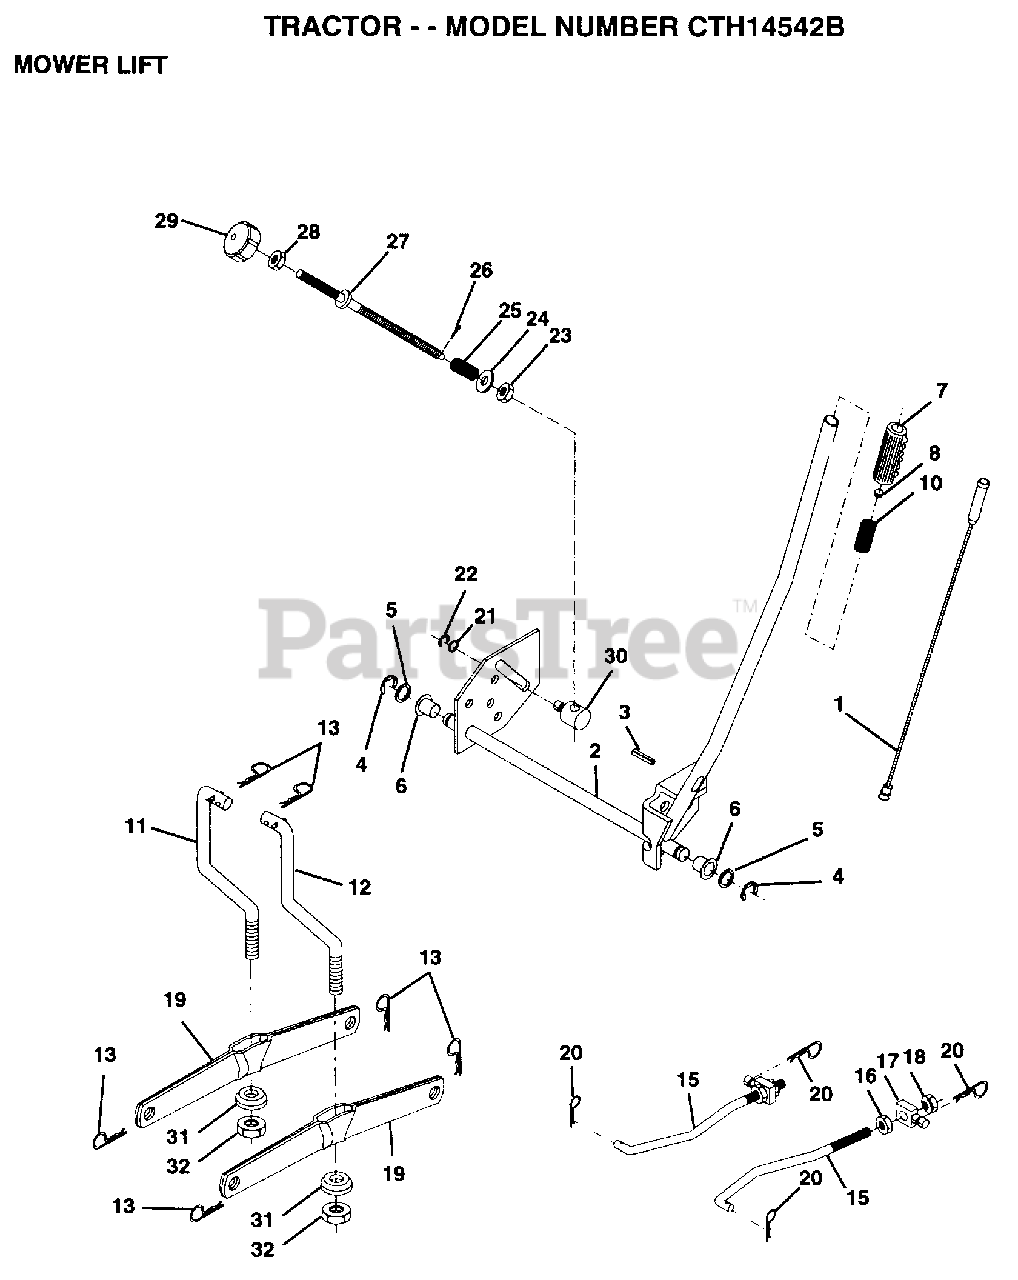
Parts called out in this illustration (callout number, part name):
1	WIRE.ASM.INNER
2	SHAFT.ASM.LIFT.RH
3	PIN GROOVE
5	WASHER
6	NYLON BEARING
7	GRIP
15	LINK.FRONT
16	NUT
17	TRUNION
18	NUT.LK.W/WSH.1/2.
19	ARM SUSP REAR
20	RETAINER.SPRING
21	WASHER
22	KLIP RING
23	NUT T
24	WASHER
25	SPRING.COMP.INF.H
27	ROD.ADJ.LIFT
28	NUT
29	KNOB INF 3/8-16
30	TRUNION LT
31	BEARING PVT LH
32	NUT.CROWNLOCK.3/8
